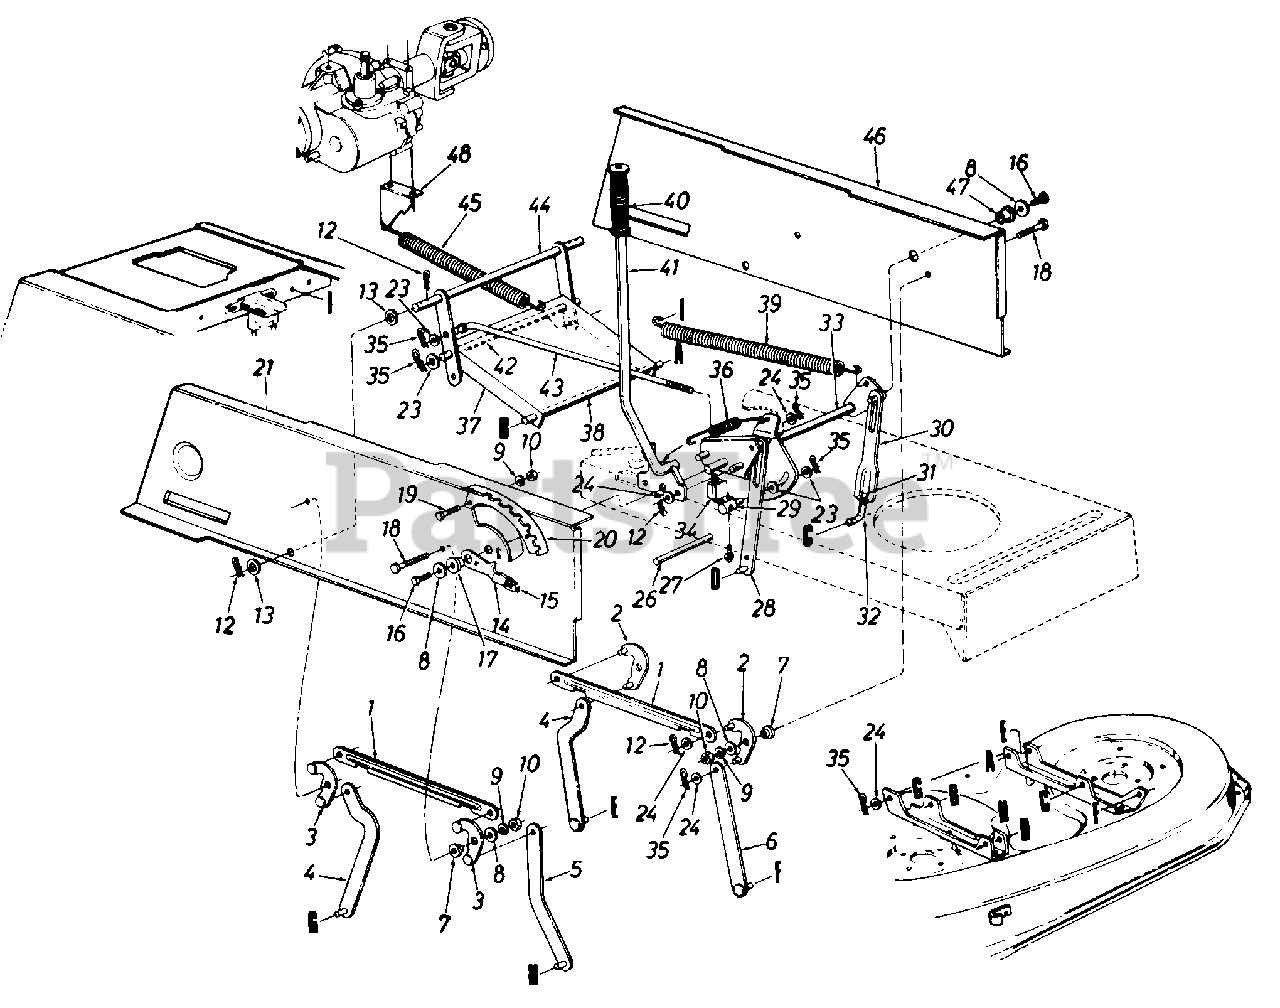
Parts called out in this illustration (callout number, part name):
1	Connecting Rod
2	Pivot Link Ass'y.-L.H.
3	Pivot Link Ass'y.-R.H.
7	Shld. Spacer.318" l.D.
8	Fl-Wash. .344" I.D. x 1.125"
9	L-Wash. 5/16" I.D.*
10	Hex Nut 5/16-18 Thd.*
12	Cotter Pin 1/8" Dia.
13	Fl-Wash. .635n l.D. x 1.0" O.D.
14	Deck Lift-Down Stop
16	Hex Wash. TT-Tap Scr. 5/16-18 x .75n Lg.
17	Flange Brg. .S3n l.D.
18	Hex Wash. TT-Tap Scr. 5/16-18 x.875" Lg.
19	Hex Bolt 5/16-18 x .75" Lg.
20	Index Brkt.
21	Upper Frame-R.H.
23	Fl-Wash. .885" l.D. x .87" O.D.
24	Fl-Wash. .531" I.D. x .93" O.D.
26	Running Board Rod
27	Truss Mach. Scr. #10 x .5" Lg.
31	Hex Nut 1/2-20 Thd. (Gr. 5)
32	Lift Link Adjuster
33	Lift Shaft Ass'y.
34	Safety Switch
35	Inter. Cotter Pin 3/8" Dia.
36	Extension Spring
37	Stabilizer Bracket
38	Shaft 1/2" Dia. x 10.28" Lg.
39	Extension Spring
40	Grip
41	Deck Lift Handle Ass'y.
42	Shaft 3/8" Dia. x 9.34" Lg.
43	Disengagement Rod
44	Stabilizer Shaft Ass'y.
45	Extension Spring 7.58" Lg.
46	Upper Frame-L.H.
47	Flange Brg. .632" I.D.
48	Spring Retainer Brkt.
